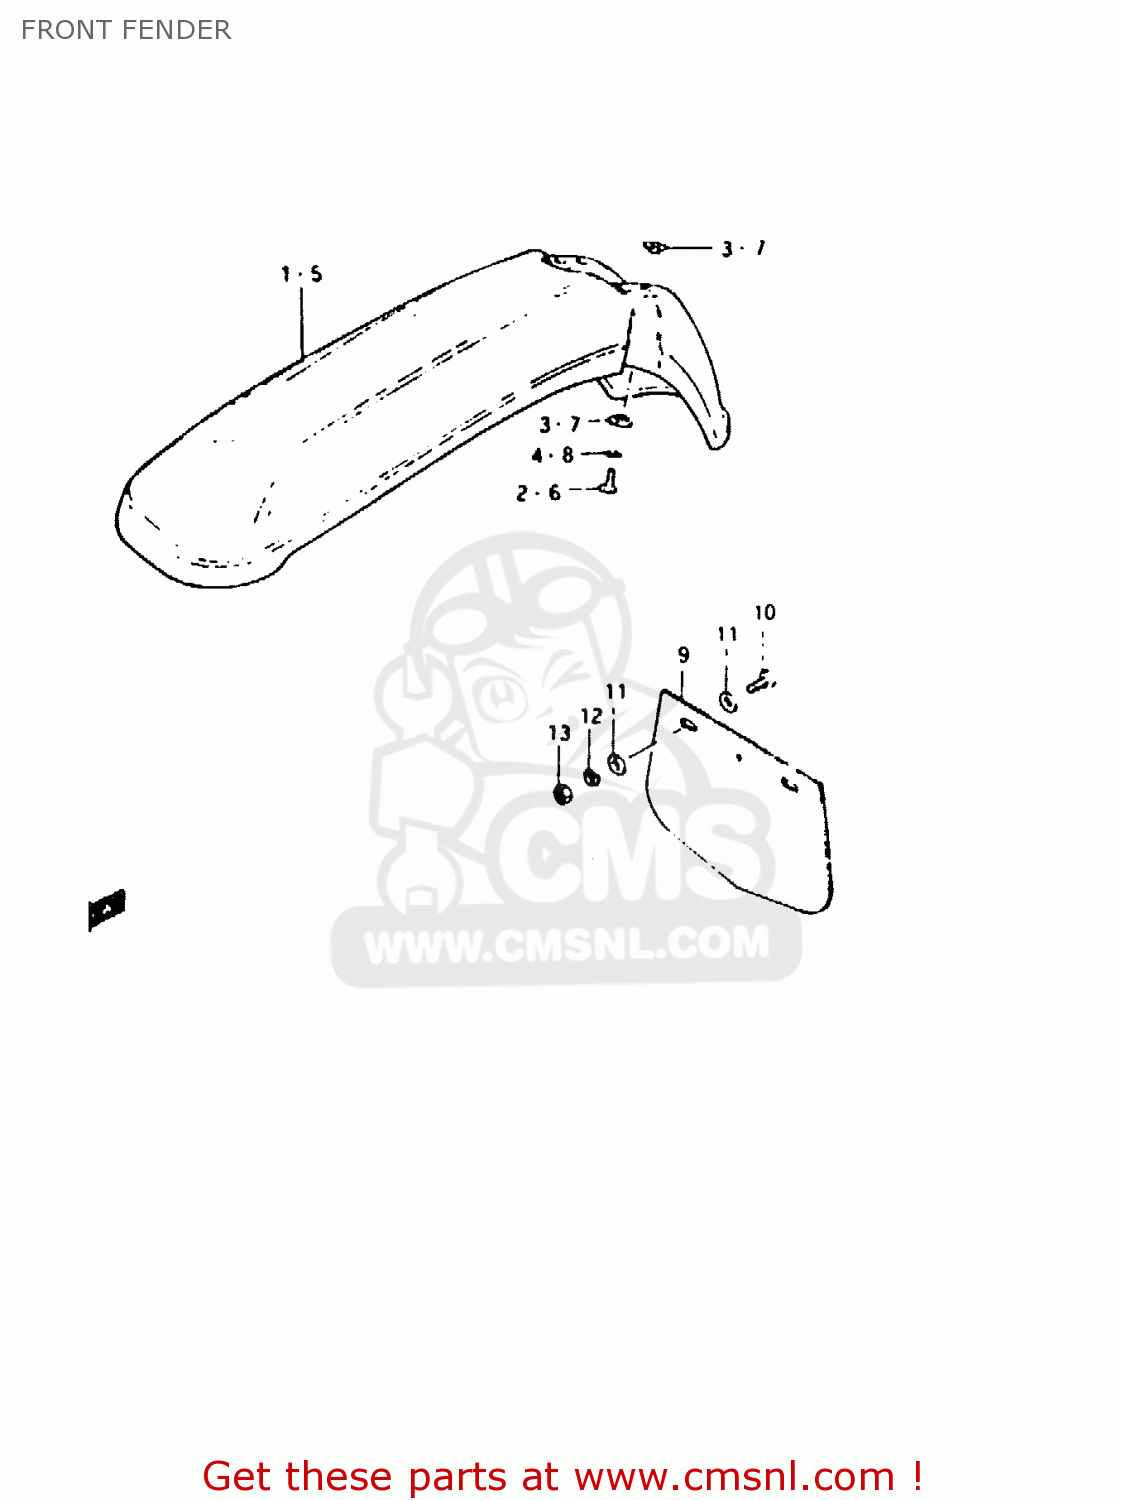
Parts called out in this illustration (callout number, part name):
1	FENDER,FRONT
2	BOLT, UPPER
3	SPACER
4	LOCK WASHER
